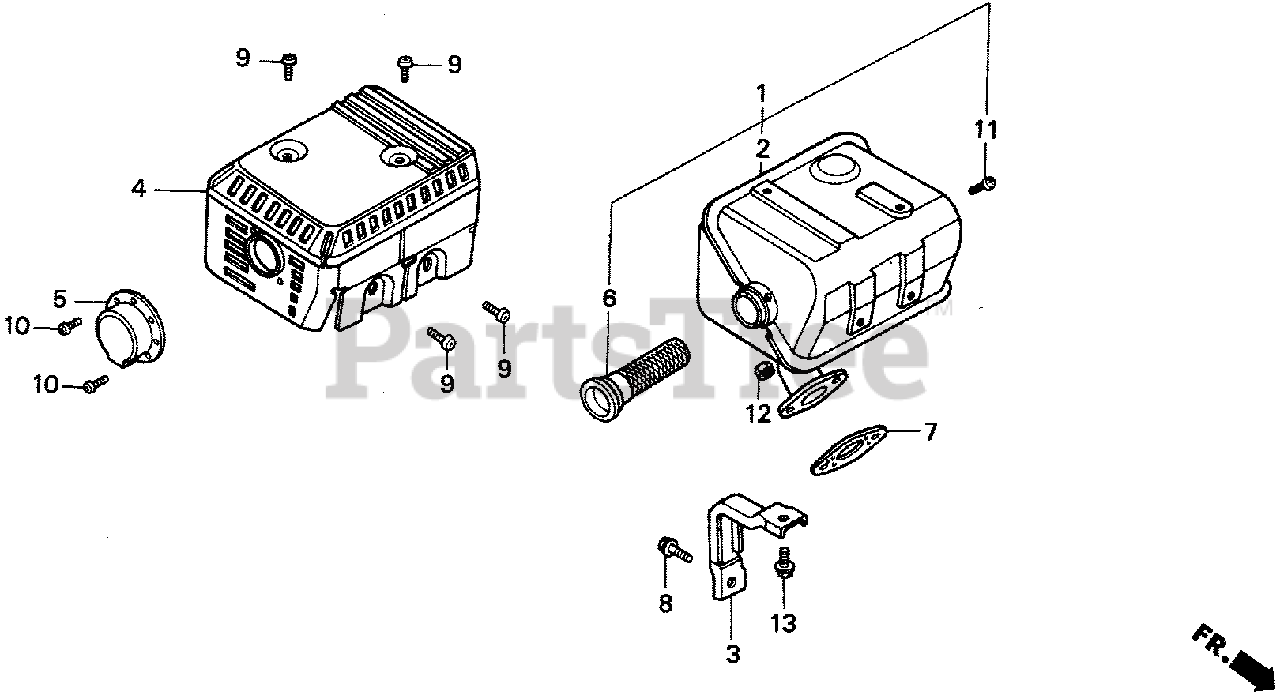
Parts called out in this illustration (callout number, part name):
2	MUFFLER (SILENT)
3	STAY, MUFFLER
4	PROTECTOR, MUFFLER
5	CAP, MUFFLER
6	ARRESTER, SPARK
7	GASKET, MUFFLER
8	BOLT, FLANGE (6X13)
9	SCREW, TAPPING (5X8)
10	SCREW, TAPPING (4X6)
11	SCREW, TAPPING (4X6)
12	NUT, HEX. (8MM)
13	BOLT, FLANGE (6X12)
